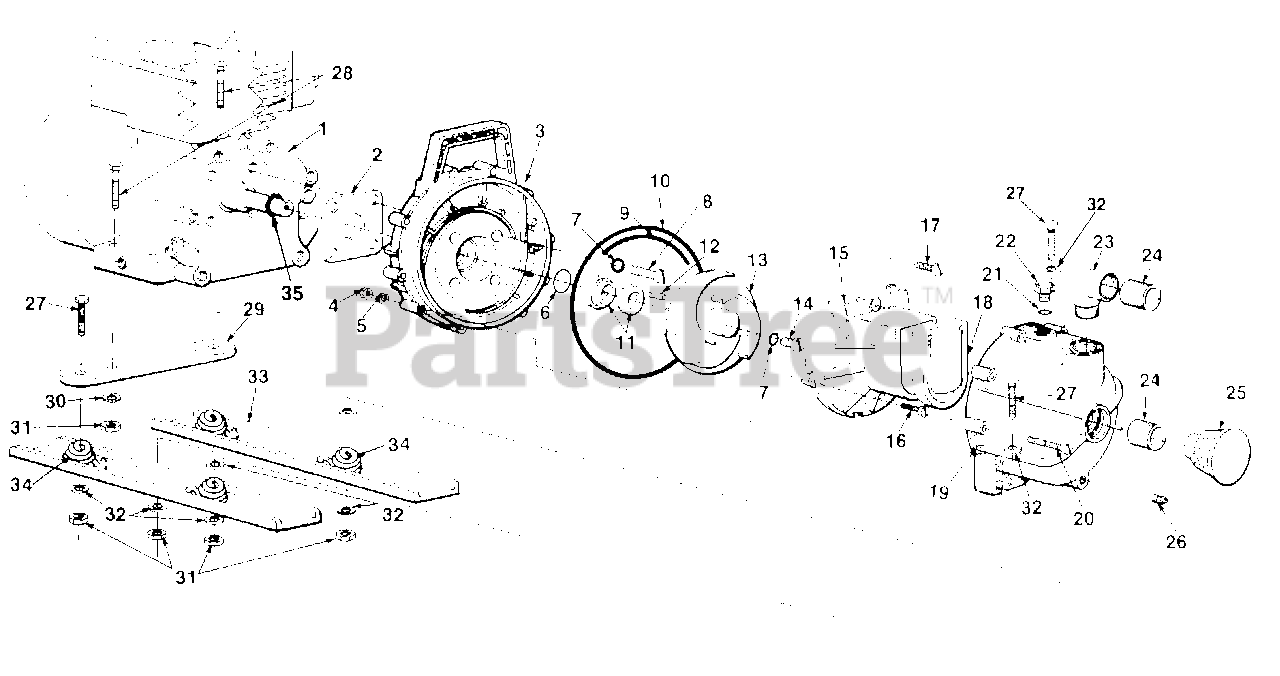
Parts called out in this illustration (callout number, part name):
1	ENGINE
3	HOUSING- Impeller
4	NUT- Hex 1/4-20
5	WASHER- Lock 1/4
6	"O" RING (Buna N)
7	"O" RING, Screw (Buna N)
8	SCREW, Bracket, impeller hsg.
9	"O" RING, Segment (Buna N)
10	"O" RING, Body (Buna N)
11	SHAFT SEAL (Buna N)
12	KEY, 3/16 x 3/16 x 1
13	IMPELLER
14	SCREW, Impeller, rd. hd. 5/16-24 x 3/4
15	VOLUTE
16	SCREW- Volute (stainless) 6-32 x 1/2 rd. hd.
17	SCREW- Volute top (10-24 x 1 1/2) rd. hd.
18	CHECK VALVE (Buna N)
19	BODY 1 1/2"
20	SCREWS- Body fil. (1/4-20 x 2 1/2)
21	"O" RING- Fil. plug (Buna N)
22	PLUG- Filler
23	ELBOW- Street, 1 1/2"
24	PIPE, Fitting, 1 1/2
25	STRAINER, 1 1/2"
26	PLUG- Drain
27	SCREW- Hex 5/16-18 x 1
28	SCREW- Engine mtg. 5/16-18 x 1 1/2
29	BAR- Mounting
30	WASHER- Lock 5/16 heavy
31	NUT- Hex hd, 5/16-18
32	WASHER- Flat, 5/16
34	SPRING- Foot
35	SLINGER
